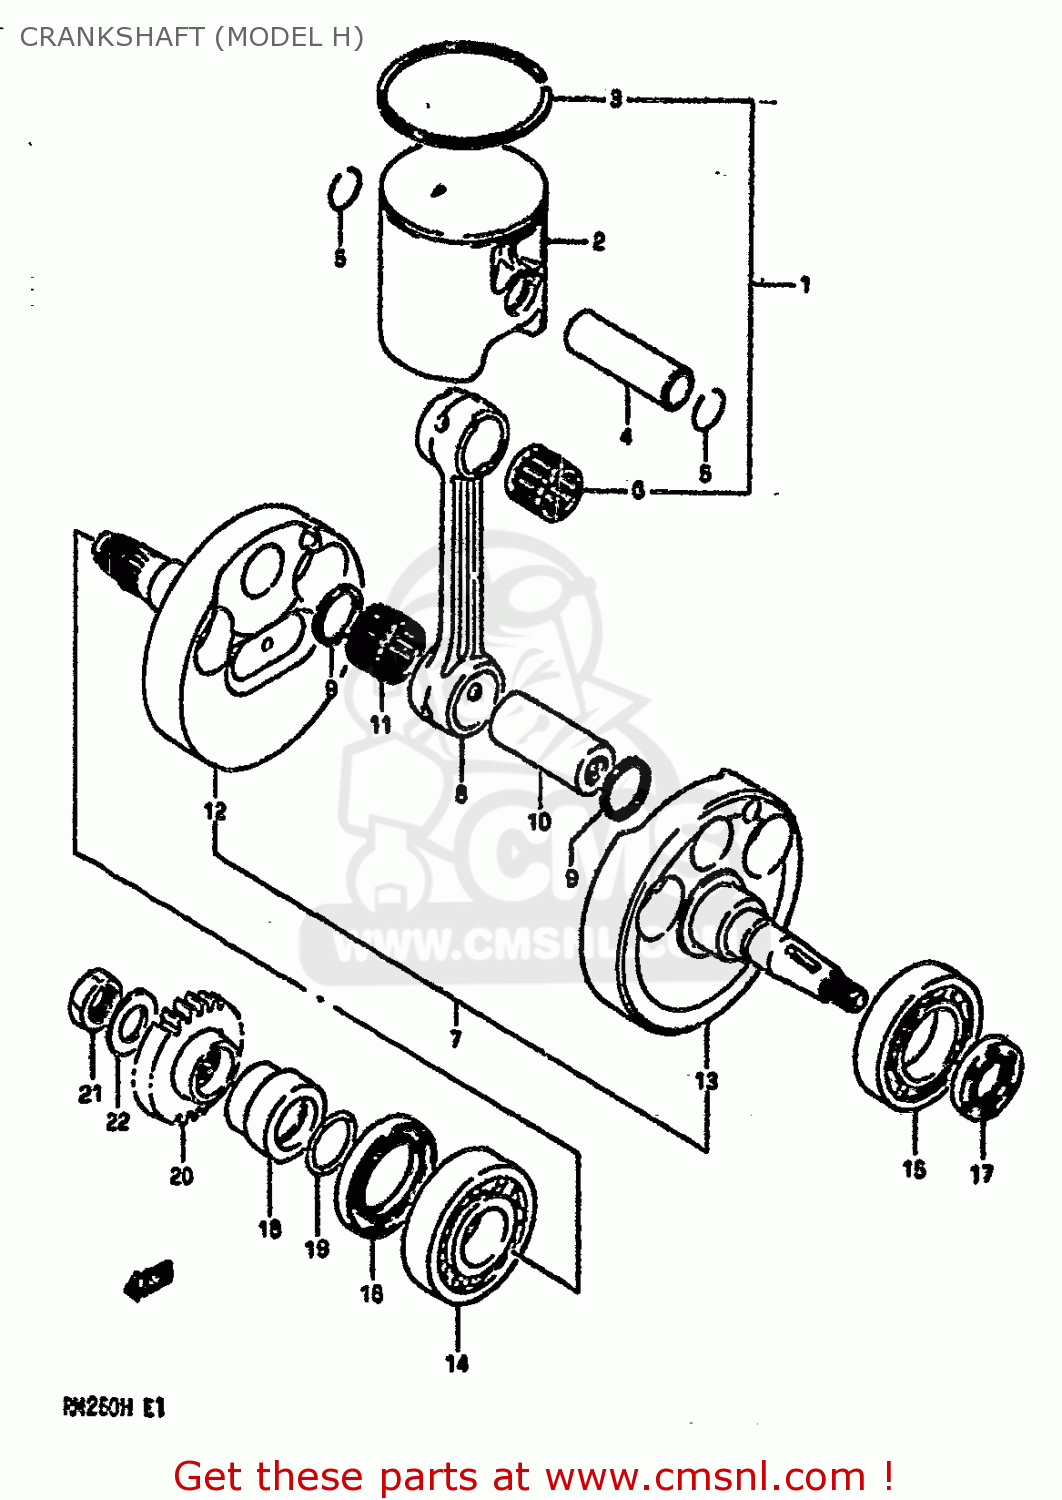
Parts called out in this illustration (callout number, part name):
1	PISTON SET (STD)
2	PISTON (67.00MM)
3	RING,PISTON
4	PIN,PISTON
5	CIRCLIP,PISTON PIN
6	BEARING(18X23X22)
7	CRANKSHAFT ASSEMBLY
8	CONNECTION ROD
9	WASHER(24X29X1.5)
10	PIN COMP,CRANK
11	BEARING
12	CRANKSHAFT,R
13	CRANKSHAFT,LEFT
14	BEARING(25X62X17)
15	BEARING(30X62X16)
16	SEAL,OIL(36X52X8)
17	OIL SEAL
18	SPACER,PRIMARY DRIVE GEAR
19	O RING(D:2.4,ID:21.8)
20	GEAR,PRIMARY DRIVE
21	NUT
22	WASHER
